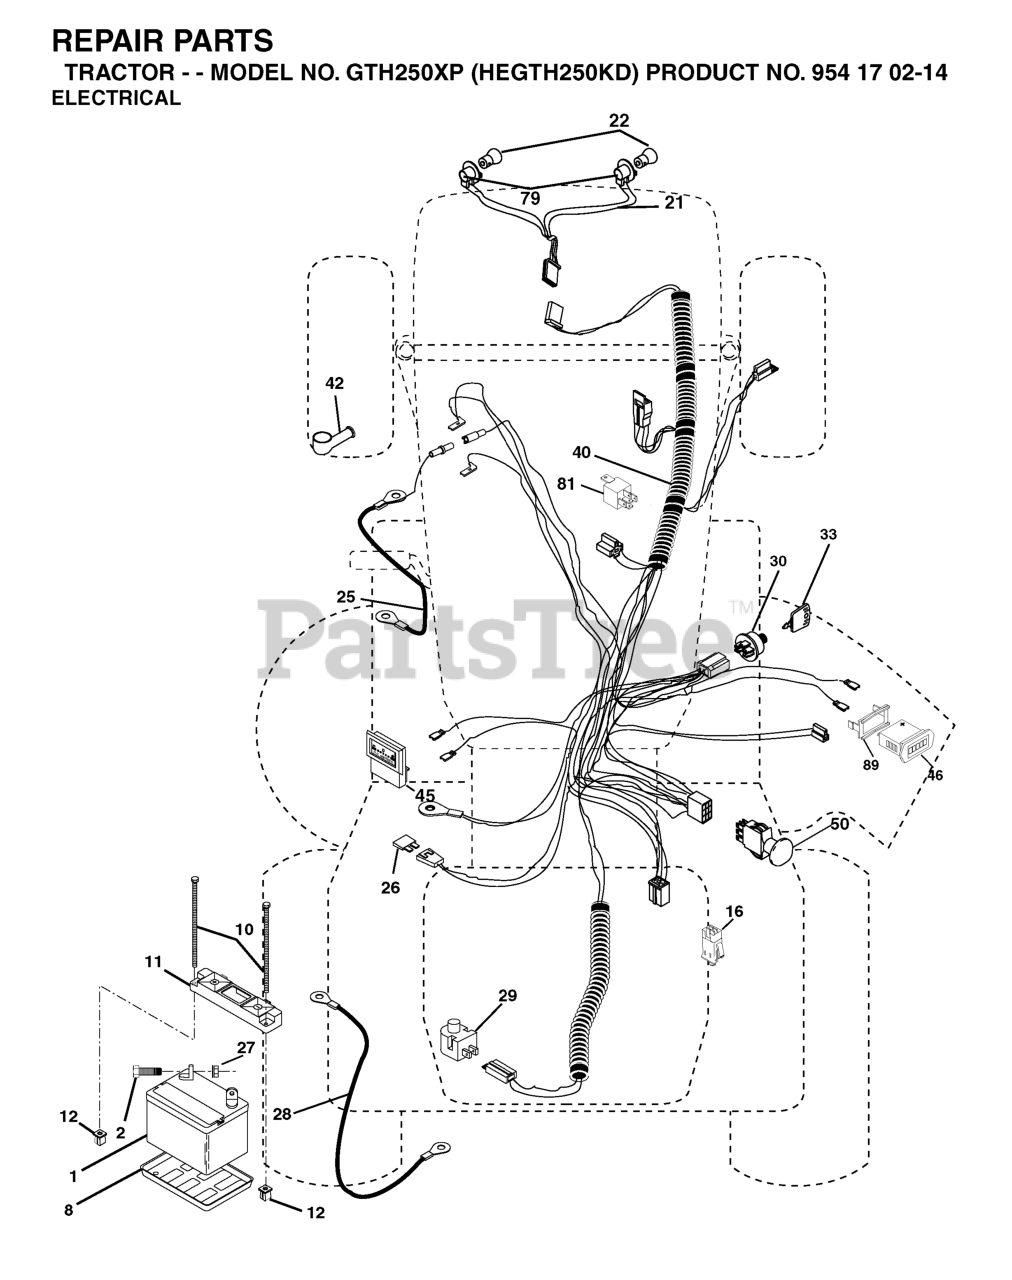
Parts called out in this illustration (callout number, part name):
1	BATTERY 12V .35 AMP
2	BOLT.HEX.1/4.X.3/4.DICHROMATE
8	BATTERY TRAY T
10	BOLT 1/4-20 X 7.5
11	BATTERY HOLDDOWN FRONT MOUNT
12	NUT, PUSH NYLON 1/4" BATTERY
16	SWITCH INTERLOOK PUSH-IN
21	HARNESS.W/LIGHT SOCKET
25	CABLE.4GA.RED.W/16GA.RED.WIRE
27	NUT
28	CABLE, GROUND
29	RP.SWITCH.PLUNGER.NC.GRAY
30	IGNITION SWITCH
33	KEY MLD GEN DELTA
42	COVER.TERMINAL.RED
46	HOUR METER
50	RP.PTO.SWITCH.8 TERMINAL.BLACK
79	BULB HOLDER ASM.
81	RELAY.ASSY.T
89	BRACKET SNAP-IN HOURMETER
